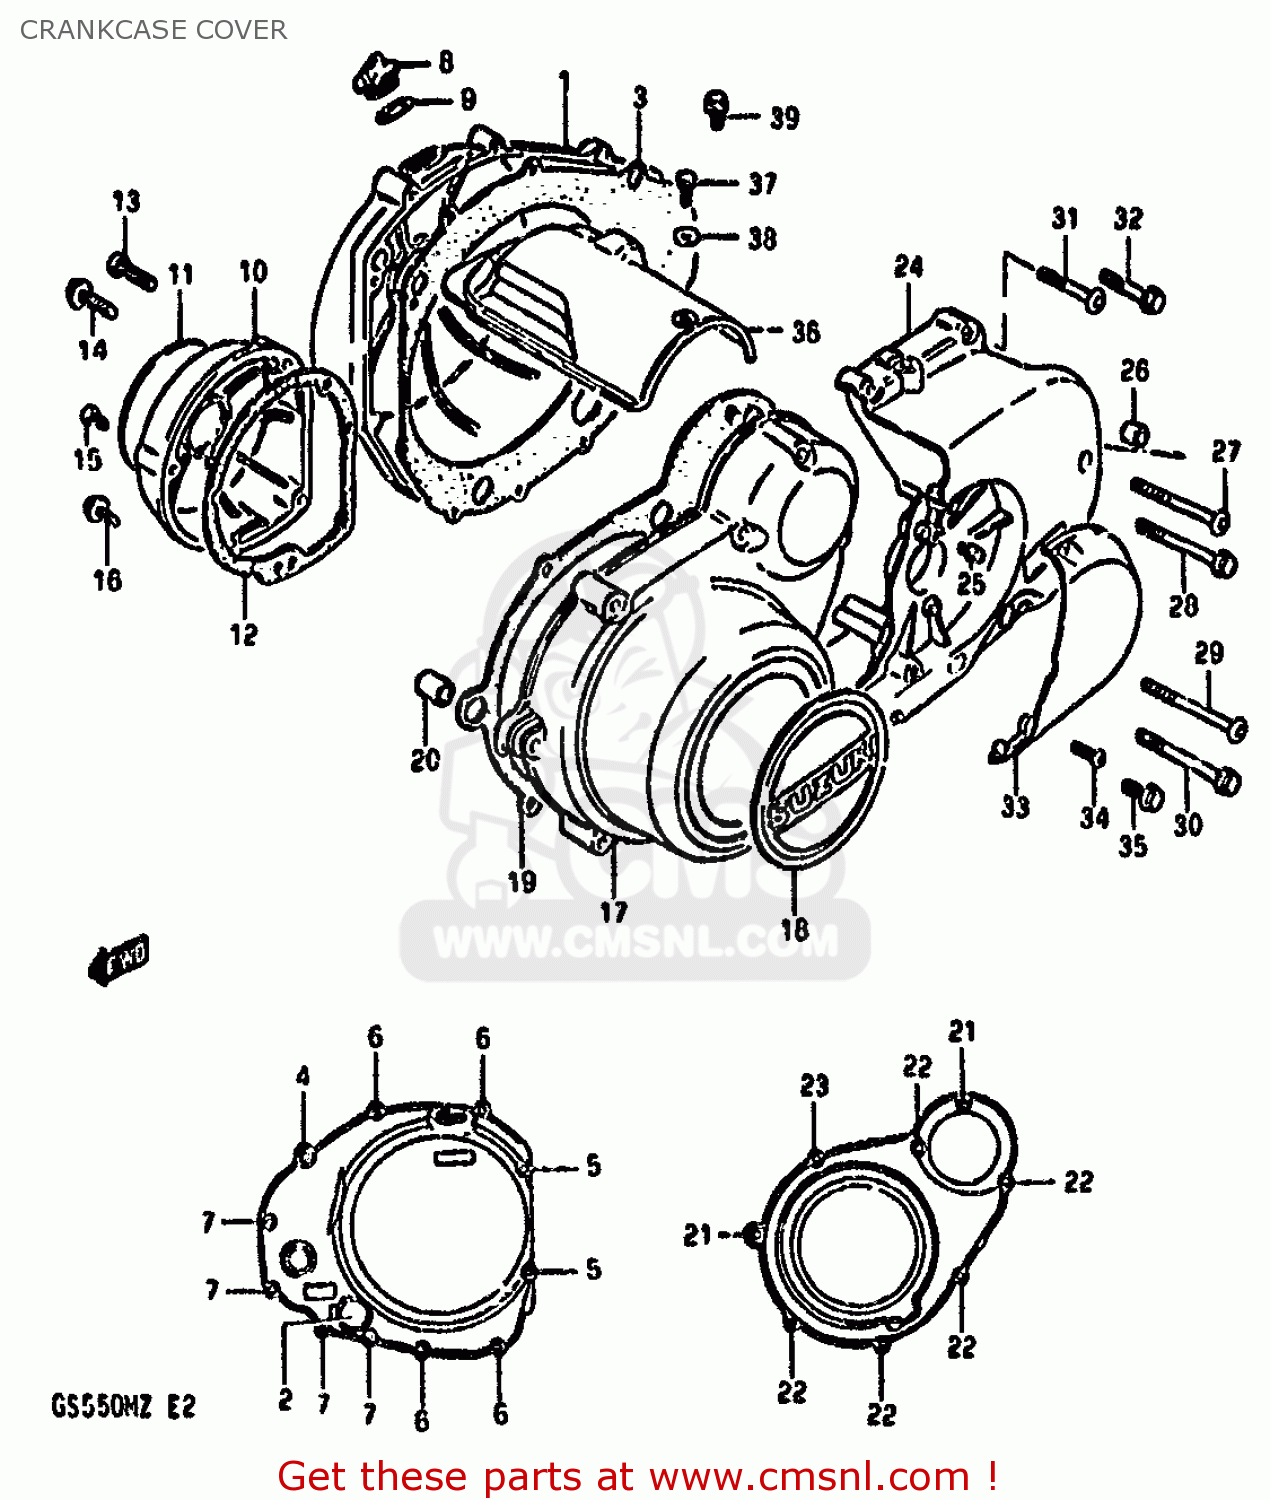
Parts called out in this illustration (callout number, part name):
1	COVER,CLUTCH
2	LENS,OIL LEVEL CHECK
3	GASKET,CLUTCH COVER (MCA)
4	BOLT (6X35)
5	SCREW
6	BOLT
7	SCREW
8	CAP
9	O RING(D:2.2,ID:32)
10	COVER,CONTACT BREAKER
11	EMBLEM,CONTACT BREAKER COVER
12	GASKET,CONTACT BREAKER COVER (NAS)
13	SCREW
14	BOLT (5*30)
15	SCREW
16	BOLT 5X16
17	COVER
18	EMBLEM,MAGNETO COVER
19	GASKET,MAGNETO COVER (MCA)
20	PIN
21	BOLT
22	SCREW
23	BOLT (6X35)
24	CRANKCASE SET
25	NIPPLE
26	PIN
27	SCREW
28	BOLT
29	SCREW 6X80
30	BOLT
31	SCREW 6X30
32	BOLT (6X30)
33	CAP,CLUTCH RELEASE ADJUST
34	SCREW
35	BOLT 5X16
36	COVER,STARTER MOTOR
37	BOLT
38	WASHER
39	BOLT (5*8)
